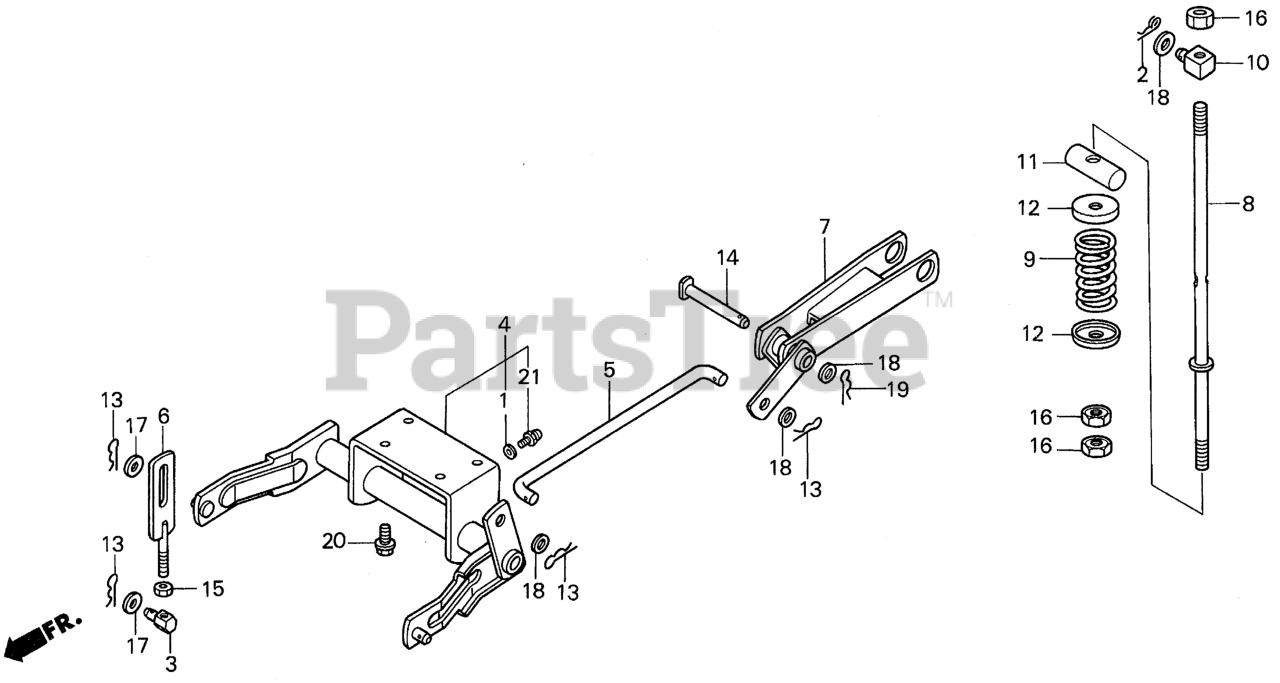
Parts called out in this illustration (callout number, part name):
1	COLLAR (6.5X11X3)
2	PIN, LOCK
3	PIN, FR. LINK ADJUSTING
4	ARM, CUTTER DECK LIFT (NOT AVAILABLE)
5	ROD, CUTTER DECK LIFT
6	PLATE, CUTTER DECK LIFT
7	LINK, CUTTER DECK LIFT (NOT AVAILABLE)
8	ROD, LIFT LINK
9	SPRING, LIFT DAMPER
10	PIN, LIFT ARM
11	PIN, DAMPER SPRING
12	WASHER (16MM)
13	PIN, LOCK (14MM)
14	PIN, LINK (LOWER)
15	NUT, HEX. (12MM)
16	NUT, HEX. (16MM)
17	WASHER, PLAIN (14MM)
18	WASHER, FLAT (16MM)
19	PIN, LOCK (16MM)
20	BOLT, FLANGE (12X25)
21	NIPPLE, GREASE (A.T6) (M6X1.0)
